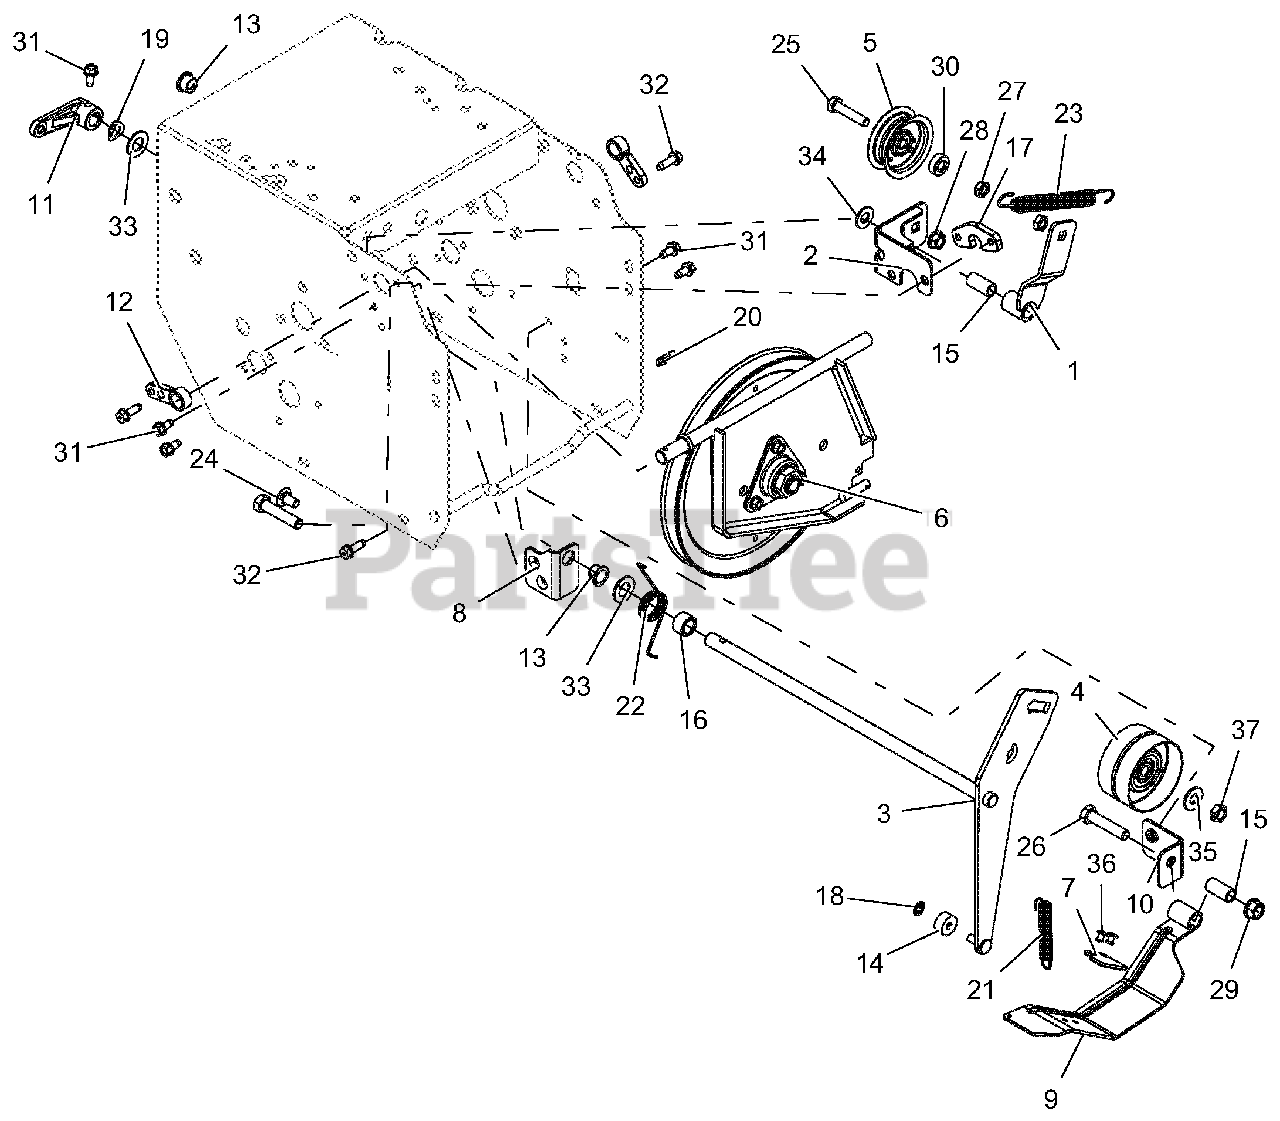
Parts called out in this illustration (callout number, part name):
1	ARM, TRACTION IDLER
2	WELDMENT, FRAME BRACKET
3	WELDMENT, ATTACHMENT IDLER ARM
4	IDLER, FLAT-2.75 OD X .375 ID
5	IDLER, FLAT - 2.00"
6	PLATE, SWING - ASSEMBLY
7	PAD, BRAKE
8	BRACKET, MOUNT - IDLER ARM
9	ARM, BRAKE
10	BRACKET, BRAKE MOUNT
11	ARM, CLUTCH - ATTACHMENT
12	SUPPORT BUSHING, SWING GATE
13	BUSHING, POLYLINER-.50 SPLIT
14	BSHG,SLV .265 X .625 X .375
15	BSHG-SLV .385X.500X1.045
16	BSHG-SLV .510X.751X.475
17	SPACER, SWING GATE
18	RG-RTNG-EXT .250X.010
19	WSHR-WAVE .50X.75X.015 .13FRHT
20	CLIP, SPRING
21	SPRING-EXT .047 X .438 X 1.85
22	SG-TORS .075 X .955
23	SPRING, SWIVEL HOOK EXTENSION
24	@BLT-RHDSSQNK .31-18X.62 G5YZ
25	@BLT-HEX .31-18X1.50 GR5 YWZC
26	@BLT-HEX .38-16X1.75 GR5 YWZC
27	@NUT-LK-CTR-JAM .31-18 YWZC
28	@NUT-LK-TOP-FLG .31-18 YWZC
29	@NUT-LK-TOP-FLG .38-16 YWZC
30	SPCR, BRG .315X.500X.358X.281
31	SCR-TAP .25-20X.50 HWH TR YWZ
32	SCR-TAP-PM .25-20X.75 TR YWZ
33	WSHR-FL-STL.531X1.00X.063 YWZC
34	@WSHR-FL-STL.406X.812X.065 YWZ
35	@WSHR-FL-STL.38X.875X.083 YWZC
36	RVT-POP .187 YZ
37	@NUT-LK-CTR-JAM .375-16 YWZC
